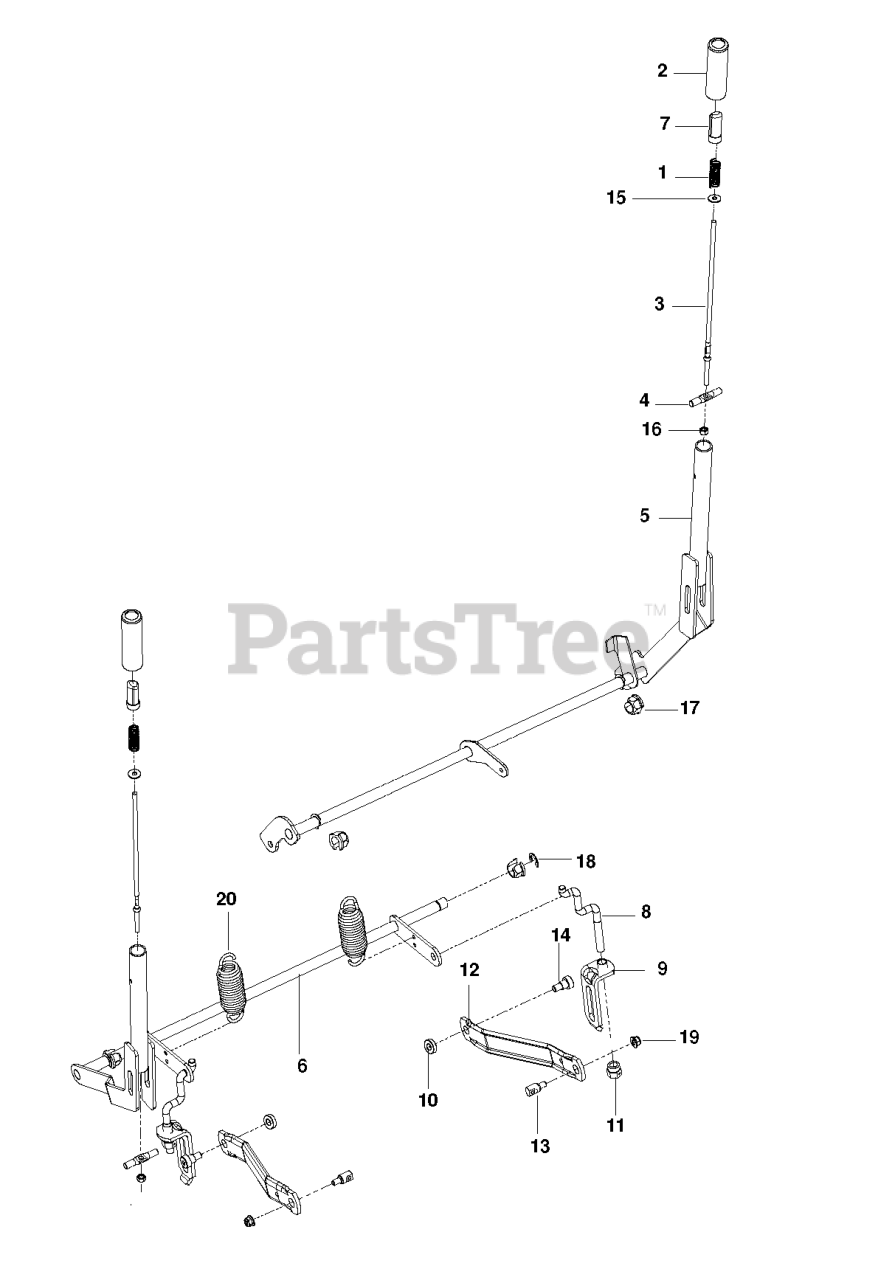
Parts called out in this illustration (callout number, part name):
1	SPRING, COMPRESSION
2	GRIP, HANDLE, BLACK 4"
3	ROD, HANDLE RELEASE
4	RB ROD, LATCH RELEASE
5	SHAFT.ASSY.BRAKE.WLDMT.BLACK
6	SHAFT, LIFT, BLACK
7	BUTTON, PUSH, BLACK
8	LINK, REAR SUSPENSION
9	ASSEMBLY, BRKT LINK
11	NUT, LIFT LINK 7/16-20
12	ARM.SUSPENSION.MOWER
13	STUD.FASTNER.W/ANTI-ROTATE
14	SB 3/8-16 X 3/8 SKT HD ZD
15	WASHER 1/4 FLAT
16	NUT.1/4-20.HEX.NYLOC.ZD
17	PLASTIC NUT
18	E-RING 5/8
19	5/16-18 NYLOC FLANGE NUT
